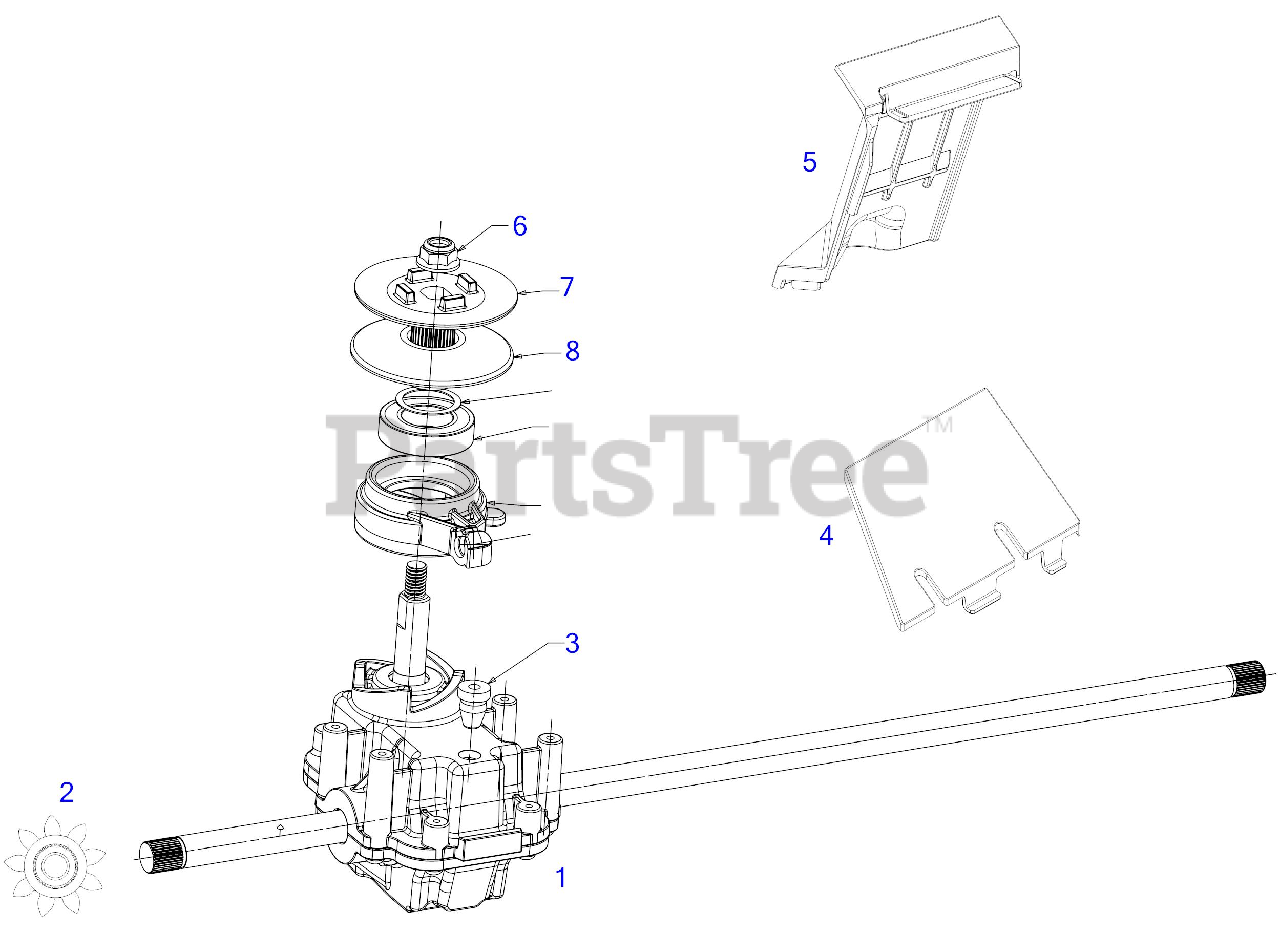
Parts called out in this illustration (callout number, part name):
1	TRANSMISSION ASSEMBLY
2	SPUR GEAR 9T
3	RUBBER PLUG
4	TRANSMISSION COVER (REAR)
5	TRANSMISSION COVER (FRONT)
6	FLANGE LOCK NUT 5/16-18
7	UPPER TRANSMISSION PULLEY
8	LOWER TRANSMISSION PULLEY
